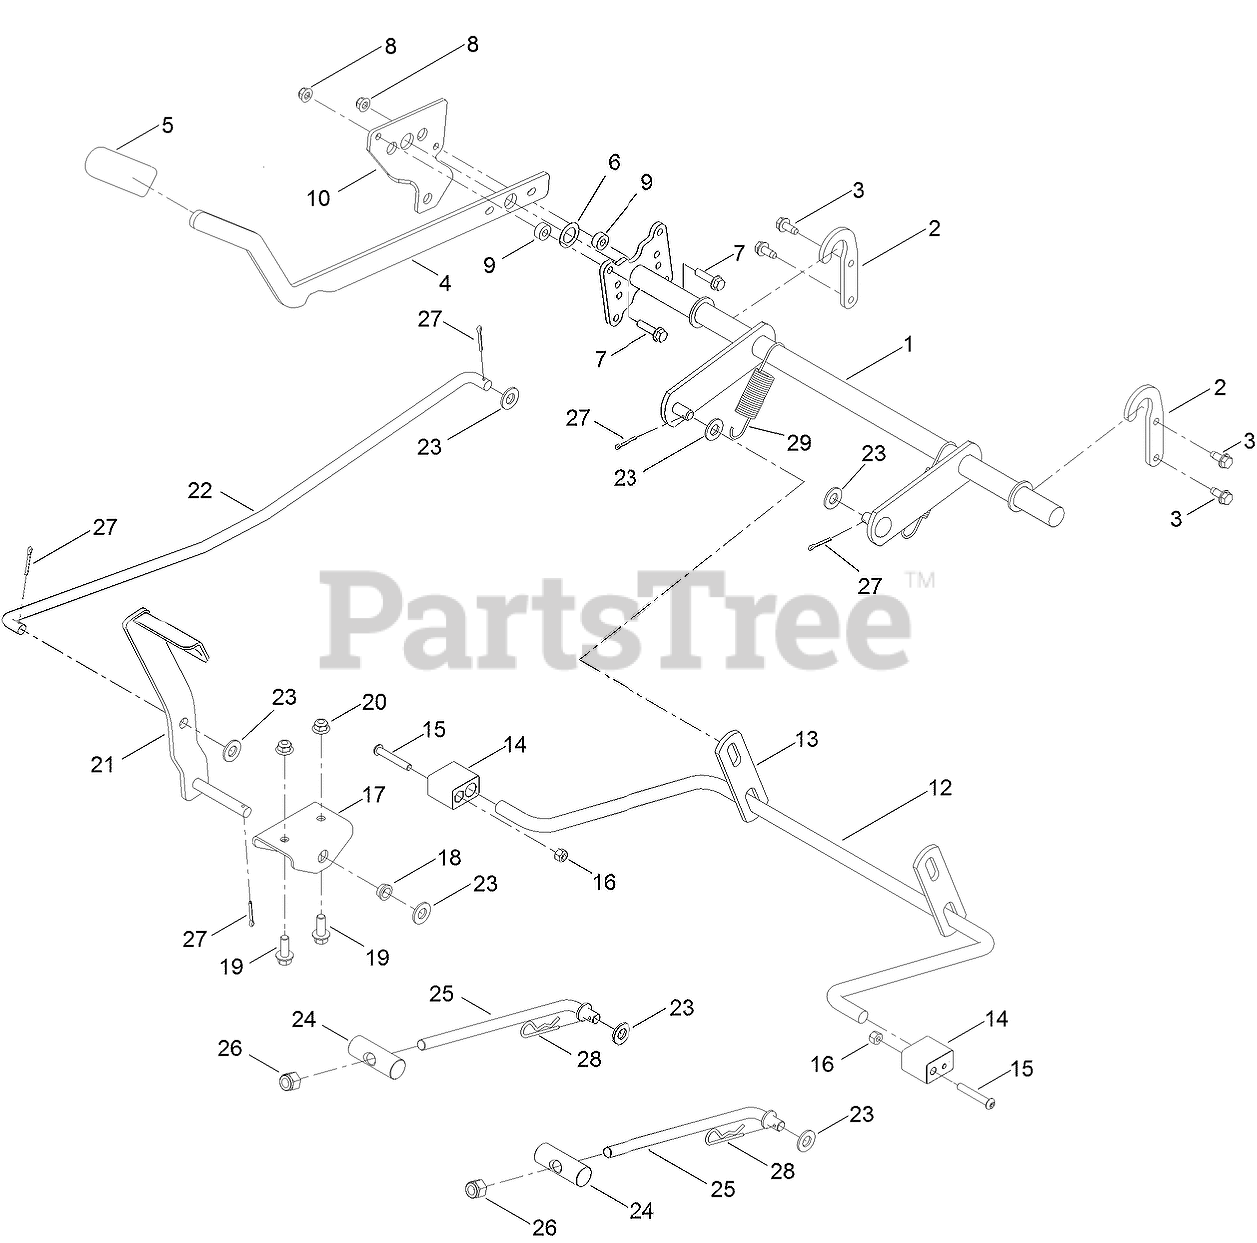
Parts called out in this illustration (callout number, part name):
1	DECK LIFT ASM
2	BRACKET-LIFT
3	SCREW-HWHTF
4	LEVER-LIFT
5	GRIP-LEVER
6	WASHER-THRUST
7	SCREW-HHF
8	NUT-HF, NI
9	SPACER
10	PLATE-FOOTLIFT
12	ARM-LIFT, REAR (WIDE)
13	LINK-LIFT
14	BLOCK-PIVOT
15	SCREW-HSBH
16	NUT-LOCK, NI
17	BRACKET-FOOTLIFT
18	BUSHING-FLANGE
19	SCREW-HHF
20	NUT-HF, NI
21	PEDAL ASM
22	ROD-FOOTLIFT
23	WASHER-FLAT
24	PIN-PIVOT
25	ROD-MOUNT, DECK
26	NUT-HEX
27	PIN-COTTER
28	PIN-COTTER
29	SPRING, EXTENSION
